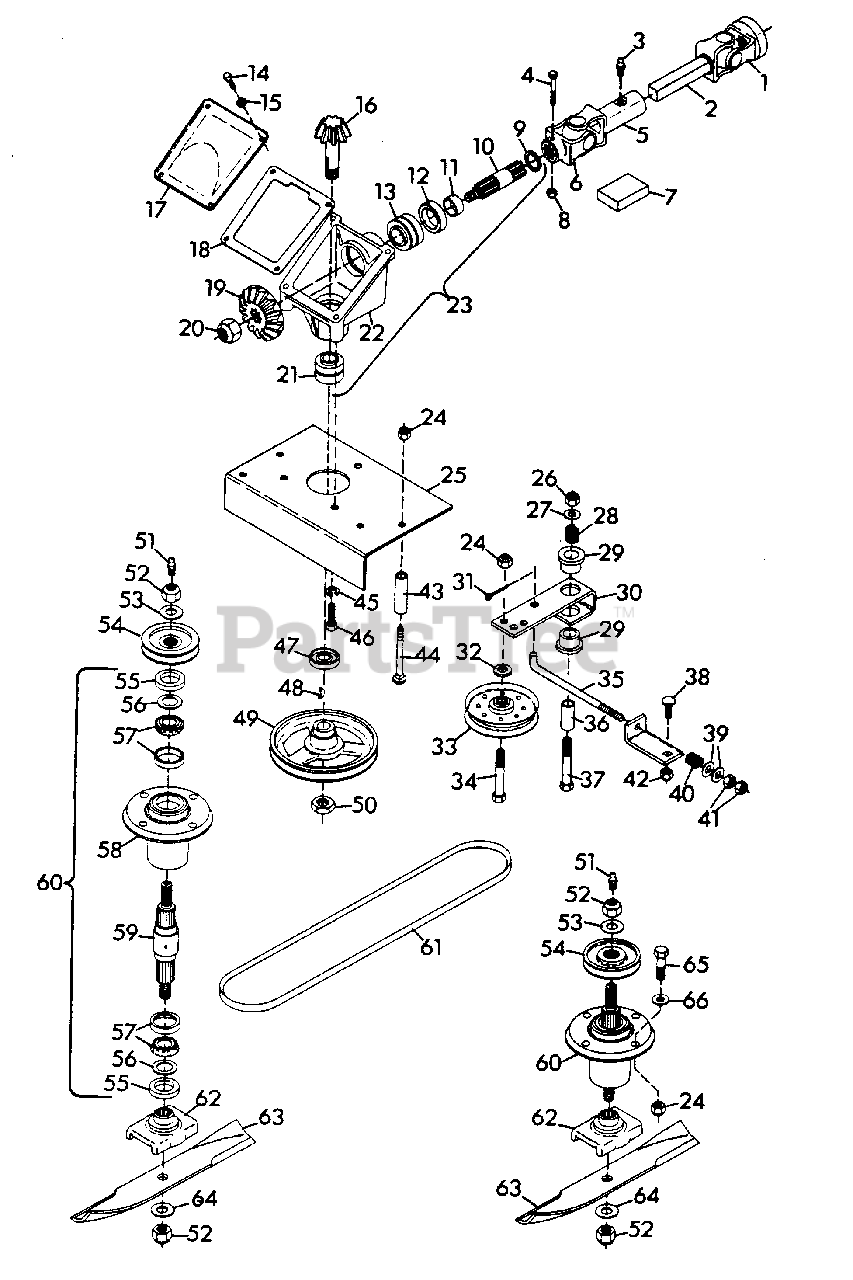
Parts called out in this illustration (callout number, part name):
1	Yoke
2	Shaft, Prop. Sq. Bar
3	Fitting, Lube 1/4-28
4	Bolt, Hex 1/4-20x2
5	U-Joint, Female End
6	Yoke(Neapco)
6	Yoke(Roscommon)
7	Kit, Repair U-Joint(Neapco)
8	Nut, Lock 1/4-20
9	Ring, Retaining 1.000 Shaft
10	Shaft, Drive
11	Spacer
12	Seal, Oil 1.250x1.987x.250
13	Assembly, Bearing
14	Bolt, Hex 1/4-20x.50
15	Washer, Lock 1/4 Reg.
16	Shaft, Gear Pinion
17	Cover, Gear Housing
18	Gasket, Gear Housing
19	Gear, Bevel
20	Nut, Lock 3/4-10
21	Assembly, Bearing
22	Casting, Gear Box
23	Assembly, Drive
24	Nut, Lock 3/8-16
25	Support, Gear Box
26	Nut, Lock 1/2-13
27	Washer, Flat .531x1.250x.100
28	Spring, Compression 1x.80x36
29	Bushing, Nylon .760x1.00x.600
30	Arm, Idler Pivot
31	Pin, Cotter .09x.75
32	Spacer, Idler. 406x.750x.188
33	Sheave, Idler
34	Bolt, Hex 3/8-16x2.25
35	Rod, Idler
36	Spacer
37	Bolt, Hex 1/2-13x3.25
38	Bolt, 3/8-16x1.00 Rd Hd Sq Nk
39	Washer, Flat .406x.812x.065
40	Spring, Compression 1.00x.78
41	Nut, Hex 3/8-24
42	Bracket
43	Spacer
44	Bolt, 3/8-16x3.50 Rd Hd Sq Nk
45	Washer, Lock 1/2 Reg.
46	Bolt, Hex 1/2-13x1
47	Seal, Oil 1.250x1.686x.313
48	Key, Woodruff .188x.625 Hd #61
49	Sheave, 1/2x6.50
50	Nut, Jam 3/4-10 Hex Heavy
51	Fitting, Lube 1/8 NPT
52	Nut, Lock 5/8-11
53	Washer, Flat .687x1.312x.122
54	Sheave, Spindle
55	Seal, Steel
56	Washer, Flat .975x1.970x.030
57	Assembly, Bearing
58	Housing, Bearing
59	Shaft, Spindle
60	Assembly, Spindle
61	Belt, 36" Mower
62	Weldment, Blade Cradle
63	Blade, 36" Mower
64	Washer, Flat .656x1.312x.095
65	Bolt, Hex 3/8-16x1.250
66	Washer, Flat .438x1.00x.083
